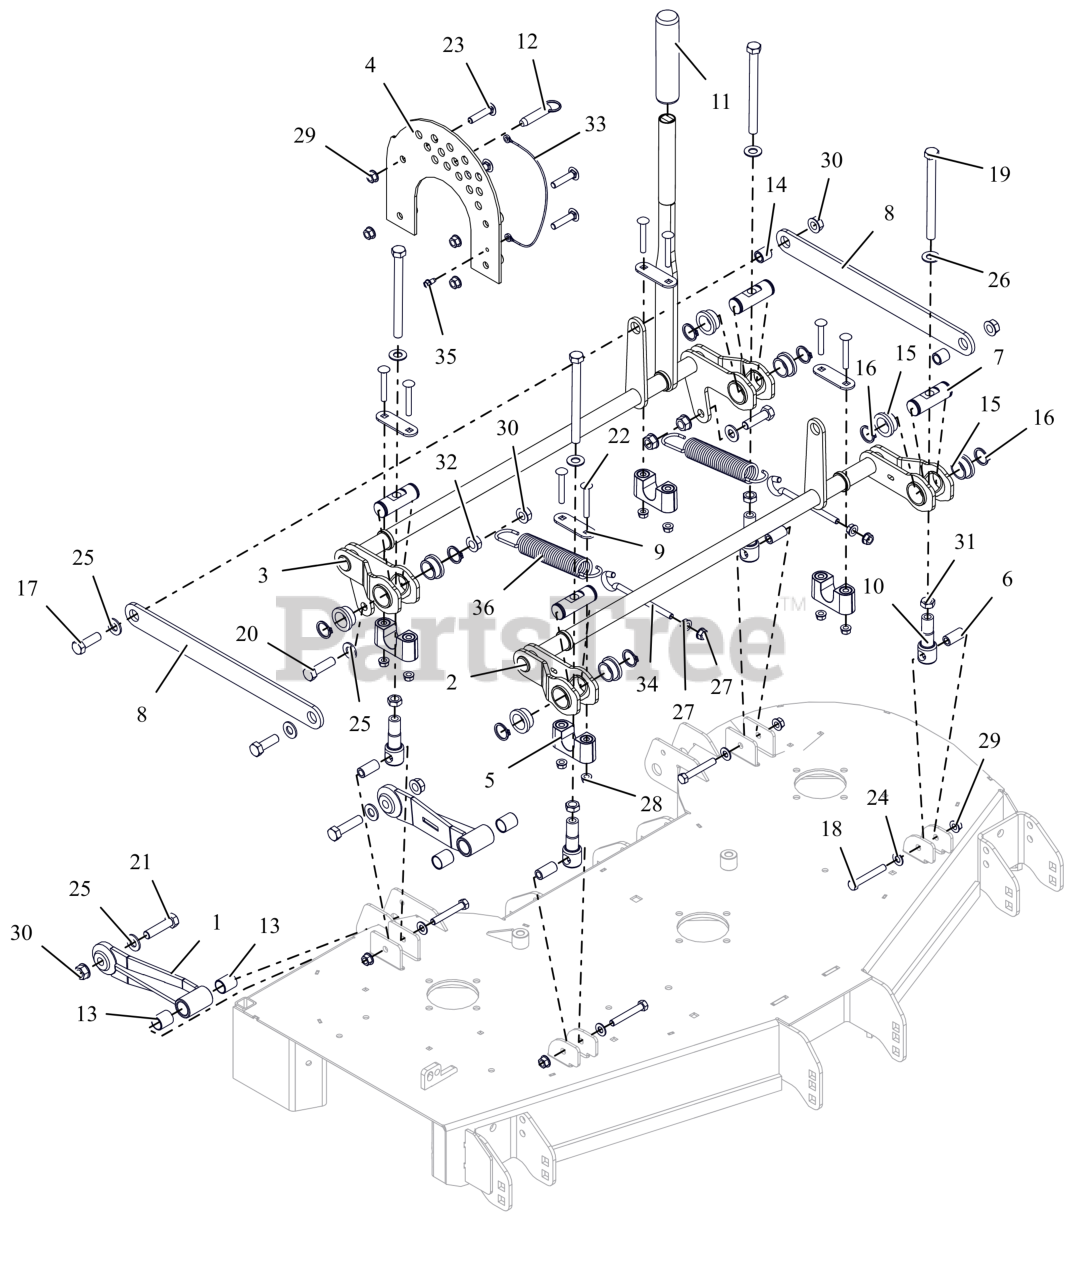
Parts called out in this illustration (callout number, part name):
1	WLDMT, PUSHER LINK BAR (BLACK)
2	WLDMT, DECK LIFT
3	WLDMT, DECK LIFT
4	WLDMT, DECK INDEXING (RED)
5	ASM-BUSHING, DECK LIFT
6	SPACER, DECK LEVELING
7	PIN, DECK LIFT
8	LINK, DECK LIFT (BLACK)
9	PLATE, BEARING SUPPORT
10	LINK, DECK LIFT FORMED
11	GRIP, DECK LIFT
12	PIN, .500 x 2.000 USABLE LG BALL
13	BRG, .750 X .875 X 1.000
14	BSHG, SLV .510 X .751 X .750
15	BSHG,FLG 1.0 X 1.25 X 1.5 X .6
16	RG-RTNG-EXT 1.00X.078
17	BLT,HEX .50-13X1.50 G5 ZCC
18	BLT, HEX .38-16X2.50 G5 ZCC
19	BLT, HEX .50-13X6.00S G5 ZCC
20	BLT, HEX .50-13X1.75 G5 ZCC
21	BLT, HEX .50-13X2.00 G8 ZCC
22	BLT, RHSSN.31-18X2.25 G5 ZCC
23	BTL,RHSSN .375-16 X 1.75 G5 ZCC
24	WSHR,FLT .406X.812X.065 ZCC
25	WSHR,FLT .531X1.062X.095 ZCC
26	WSHR, FLT .557X1.040X.102 ZCC
27	NUT, SPNLK-FLG .38-16 G5 ZCC
28	NUT,LK-CTR-FLG .31-18 GF ZCC
29	NUT-LK-CTR-FLG .375-16 GF ZCC
30	NUT-LK-CTR-FLG .500-13 GG ZCC
31	NUT-JAM .500-13 G2 ZCC
32	NUT, SPNLK-FLG .50-13 G5 ZCC
33	CABLE, 12.0 LANYARD, NYLON
34	BOLT,.38-16 X 4.25-.62 DIA EYE
35	SCR-TAP .25-20X.50 HWH ZCC
36	SG-TENS .162X1.25X8.25 WLD 25
